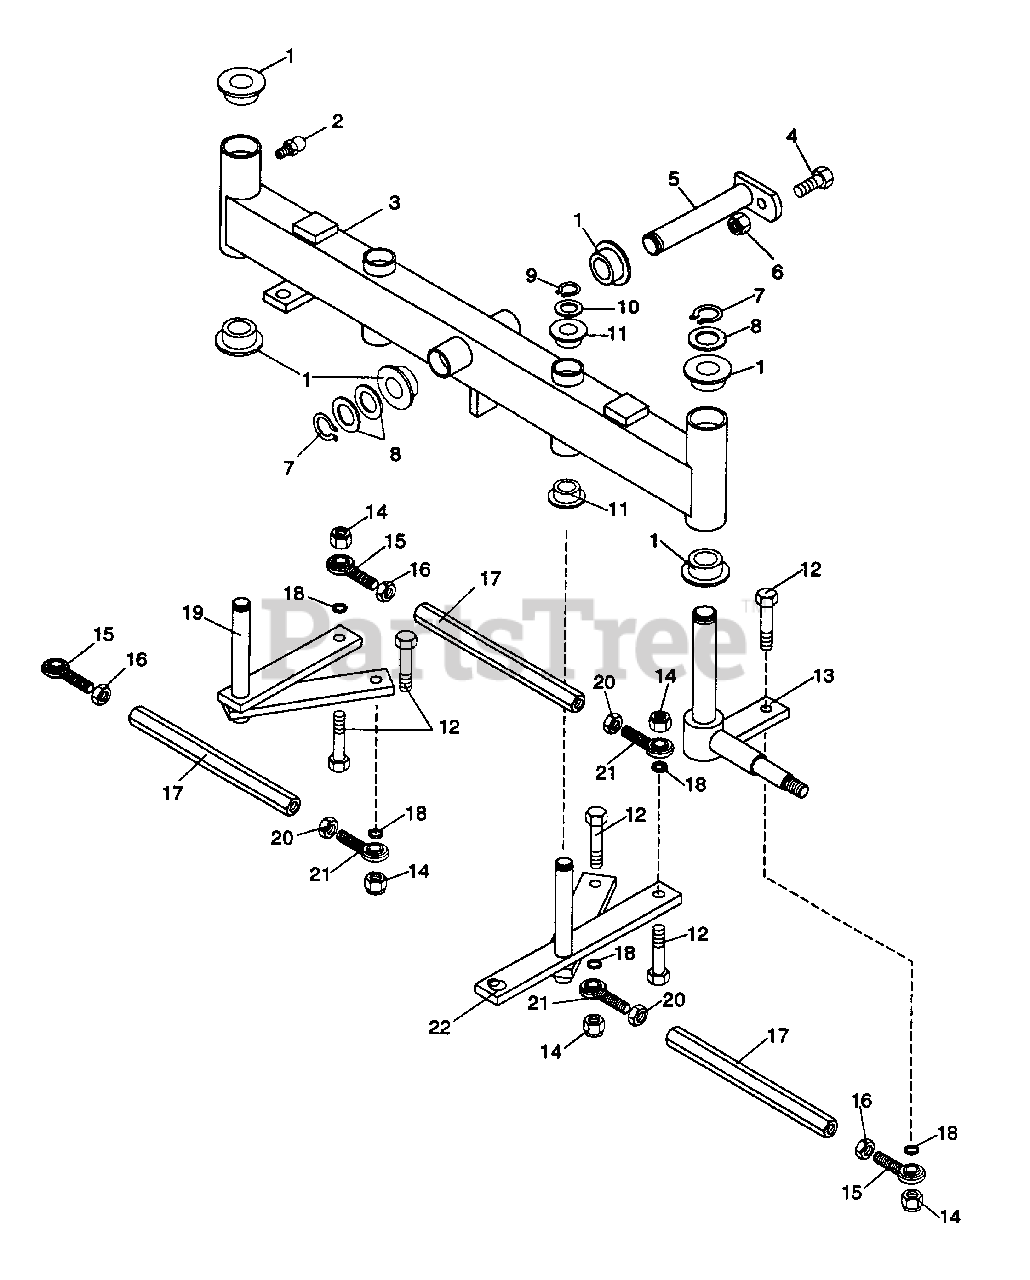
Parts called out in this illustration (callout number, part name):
1	BSHG-FLG 1.020 X 1.385 X .75 X 1.75 NY
2	FTG, LUBE; .25-28 SELF THREAD
3	WLDMT, AXLE
4	BLT-HEX .38-16 X 1.00 PI GR 5
5	WLDMT, AXLE PIN
6	NUT-LK-NYL .375-16 PI
7	RG-RTNG-EXT .906 X .078
8	BRG-NEEDLE .688 X .876 X .63
9	RG-RTNG-EXT .689 X .077
10	BRG-N-THRST .752 X 1.24 X .031
11	BSHG-FLG .762 X 1.0 X .580 X 1.48 NY
12	BLT-HEX .50-13 X 2.00 PI GR 5
13	WLDMT, KINGPIN RH
13	WLDMT, KINGPIN LH
14	NUT-LK-NYL .50-13 PI
15	ASM, ROD END RH
16	NUT-JAM .50-20 PI
18	BUSH., S .520 X .625 X .125 ST
19	WLDMT, STEERING IDLER
20	NUT-JAM .50-20 LH THD PI
21	ASM, ROD END LH
22	WLDMT, STEERING ARM
